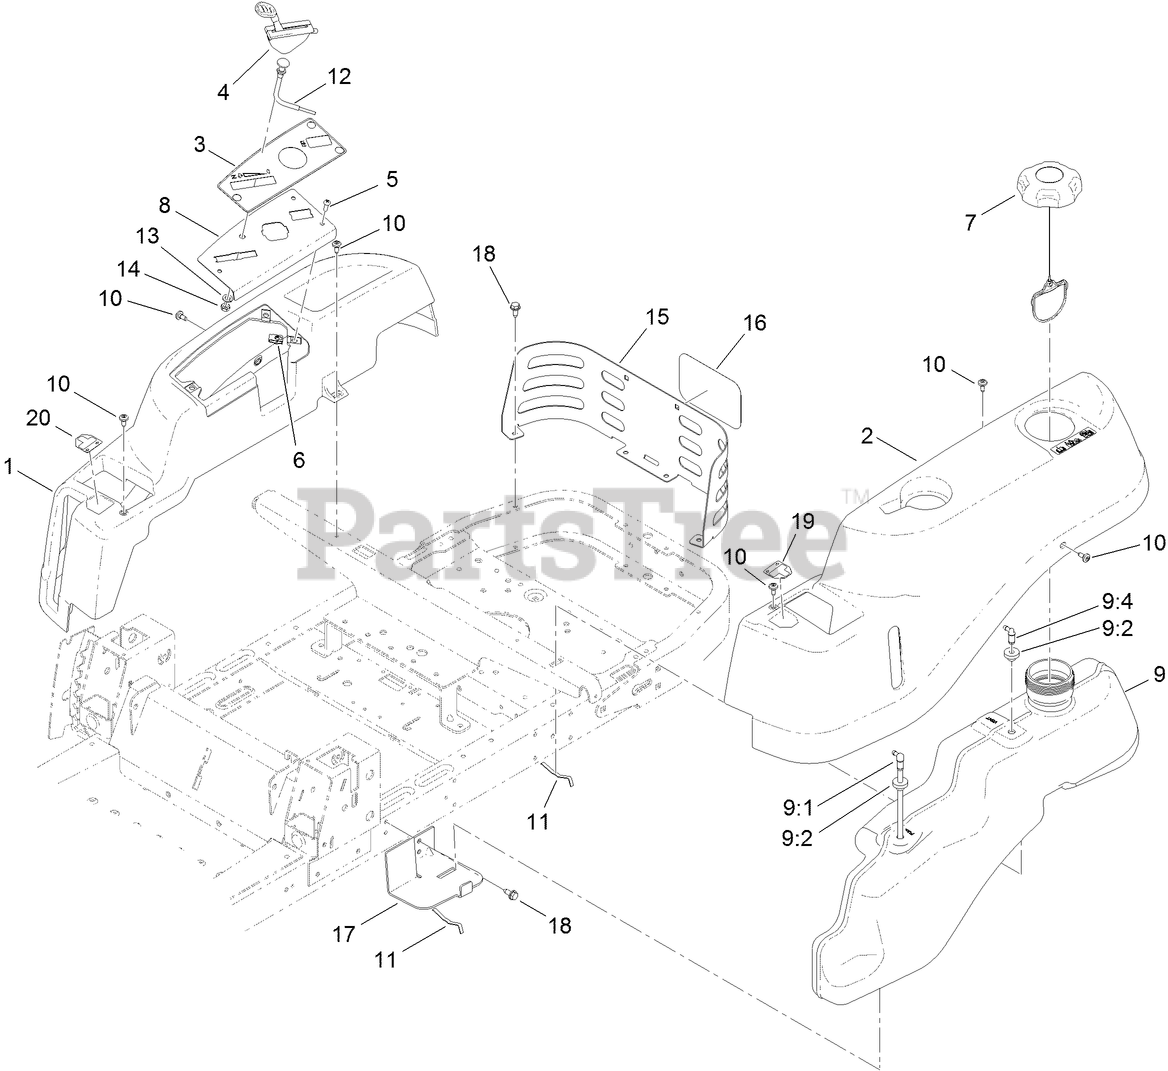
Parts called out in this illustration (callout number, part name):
1	POD-RH
3	DECAL-PANEL, CONTROL
4	CABLE-THROTTLE
5	SCREW-PRH
8	PLATE-CONTROL
9	FUEL TANK ASM
9:1	CONNECTOR-ELBOW, 90 DEG
9:2	BUSHING
9:4	FITTING-PLASTIC
10	SCREW-SHOULDER
11	SPRING
12	CABLE-CHOKE
13	WASHER-LOCK
14	NUT-HJ
15	GUARD-REAR
17	SUPPORT-TANK, FRONT
18	SCREW-HWHTF
19	DECAL-LEVER, CONTROL (LH)
20	DECAL-LEVER, CONTROL (RH)
